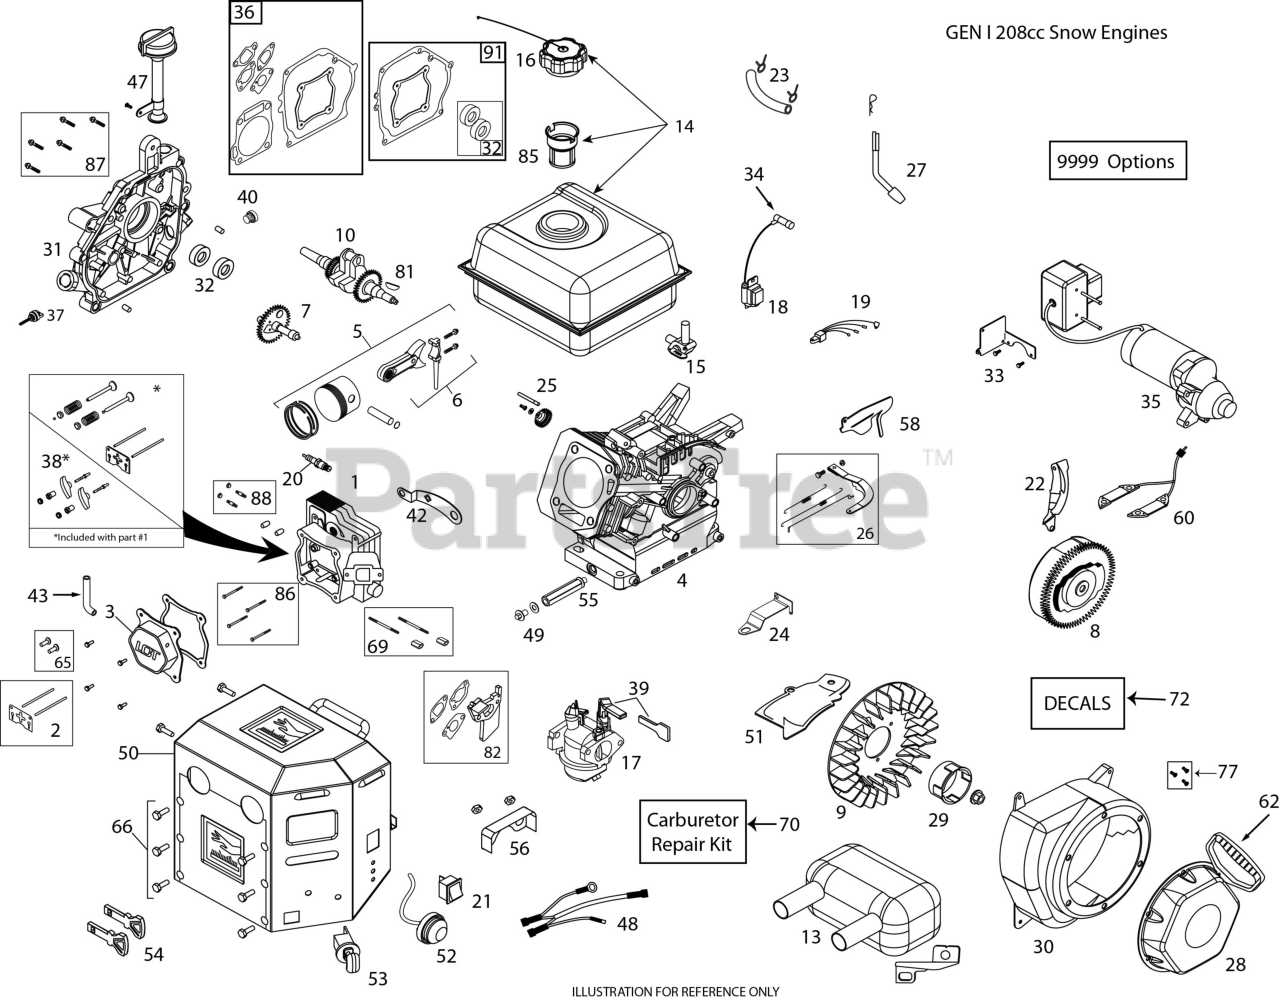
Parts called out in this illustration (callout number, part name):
1	CYLINDER HEAD ASSY (W/GASKET)
2	PUSH ROD & PLATE KIT (W/GASKT)
3	VALVE COVER (W/GASKET)
5	PISTON & ROD ASSEMBLY
6	CONNECTING ROD ASSEMBLY
7	CAMSHAFT - MCR
8	FLYWHEEL - ELECTRIC START
9	COOLING FAN - FLYWHEEL
10	CRANKSHAFT (#18 KEYED)
13	MUFFLER ASSEMBLY
14	FUEL TANK (NO LONGER AVAILABILE)
15	FUEL TANK ON/OFF VALVE (1/4")
16	CAP, FUEL TANK (BLACK)
17	CARBURETOR (W/GASKETS)
18	IGNITION COIL ASSY COIL & CDI
19	CDI MODULE - BLACK BOX
20	SPARK PLUG, ARIENS AX
21	ON/OFF SWITCH - ROCKER (RED)
22	SHIELD - FLYWHEEL ELECT START
23	FUEL HOSE KIT 1/4-318MM
24	SPEED CONTROL BRACKET (FIXED)
25	GOVERNOR GEAR ASSEMBLY
26	GOVERNOR ARM & LNK KIT 3600RPM
27	GOVERNOR ARM PADDLE
28	RECOIL STARTER ASSY HEX-BLACK
29	STARTER CUP HEX STYLE STARTER
30	BLOWER HOUSING (W/WELDNUT)
31	CRANKCASE COVER ASSY W/GASKET
32	OIL SEAL KIT(2 PCS 3/4" CRANK)
33	ELECT START SWITCHBOX BRACKET
34	SPARK PLUG
35	120V ELECTRIC STARTER
36	ENGINE GASKET KIT
37	SMALL BLACK OIL DIPSTICK
38	ROCKER ARM KIT (W/GASKET)
39	CHOKE LEVER/CHOKE HANDLE (RED)
40	NON-REMOVABLE PLASTIC PLUG
42	CDI BOX MTG BRACKET
43	BREATHER TUBE
47	HIGH OIL-FILL TUBE/DIPSTICK
48	WIRE HARNESS
49	OIL DRAIN PLUG (W/WASHER)
50	HEATER BOX KIT
51	SHIELD - CYLINDER
52	PRIMER BULB WITH HOSE-SNOW (RED)
53	SAFETY KEY SWITCH (W/KEYS) (RED)
54	KEY, PUSH/PULL LCT (2/PACKAGE)
55	OIL DRAIN TUBE
56	CARBURETOR VAPOR SHIELD
58	SHIELD - GOVERNOR LINKAGE
60	CHARGING COIL (6-WATT AC)
62	STARTER GRIP
65	TAPPET KIT (SET OF 2)
66	BOLT KIT - HEATER BOX
69	CARBURETOR STUDS & COUPLNG KIT
70	CARBURETOR REPAIR KIT
77	RECOIL BOLT KIT
81	WOODRUFF FLYWHEEL KEY 5-PACK
82	CARBURETOR SPACER
85	FUEL TANK STRAINER
86	HEAD BLT KIT 136-179-208-254CC
87	CC COVER BLT KIT 179-208-254CC
88	MUFFLER MTG STUD KIT
91	CRANKCASE GASKET KIT 208GEN1&2
9999	HIGH ALT JET-208CC L10-1 CARB
9999	OIL, ARIENS 5W30 32 OUNCE, SYNTHETIC BLEND
